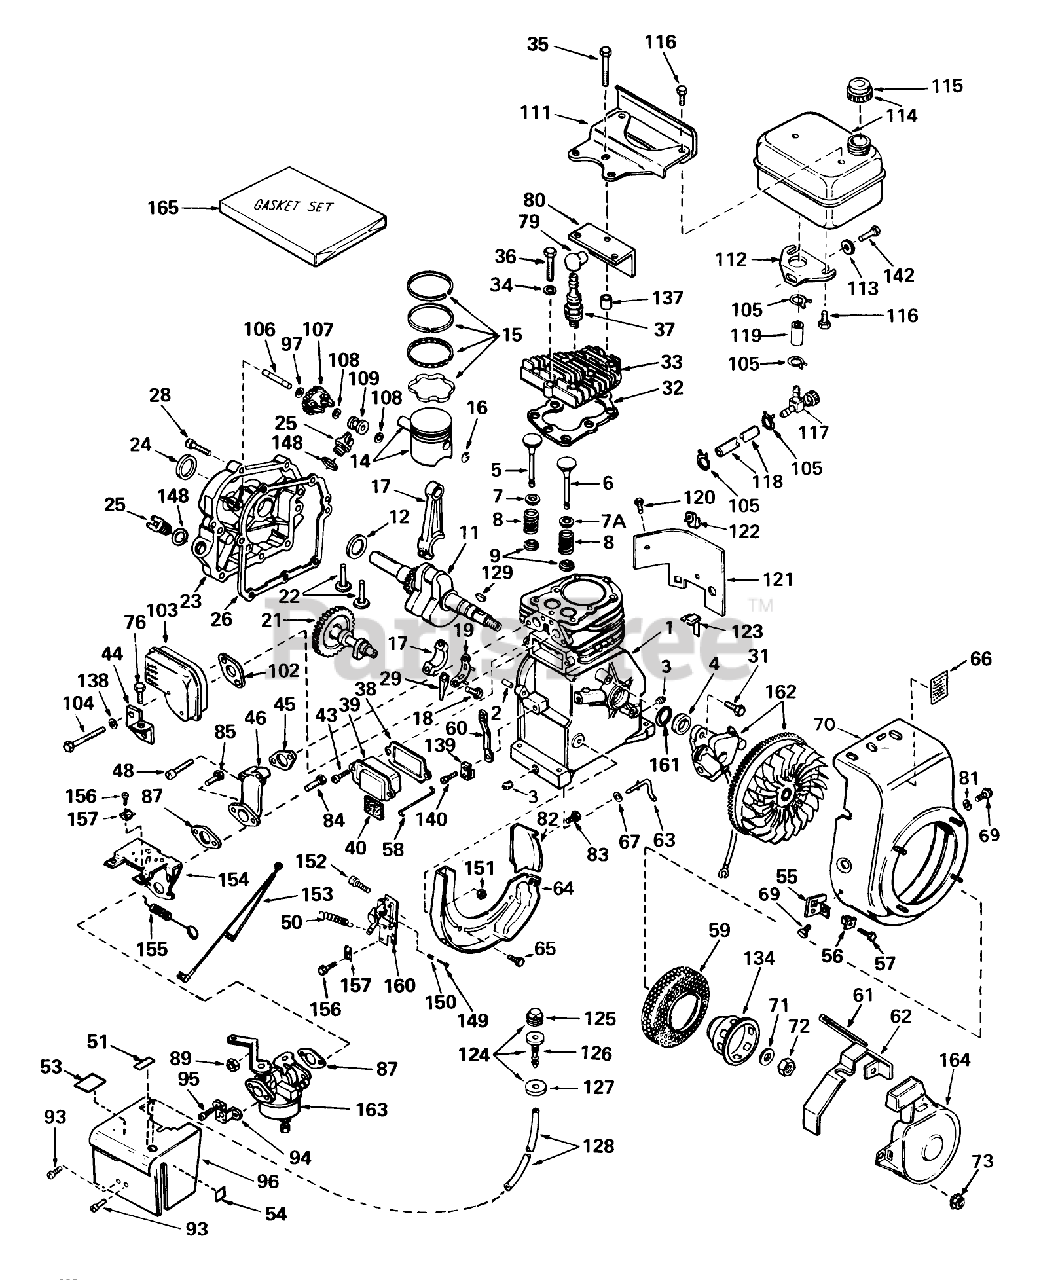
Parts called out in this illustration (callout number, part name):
1	Cylinder Assy. (Incl. Nos.2, 34)
2	Pin-Dowel
3	Plug-Drain, Oil (SQH 1/4-18)
4	Seal-Oil
5	Valve, Intake (Standard) (Incl. Nos. 7, 9 10)
5	Valve, Intake (1/32" Oversize) (Incl. Nos. 7, 9 10)
6	Valve, Exhaust (Standard) (Incl. Nos. 8, 9 10)
6	Valve, Exhaust (1/32" Oversize) (Incl. Nos. 8, 9 10)
7	Cap-Upper Valve Spring
7A	Cap, Upper Valve Spg (Exhaust)
8	Spring-Valve
9	Cap-Valve, Spring
11	Crankshaft Assy.
12	Washer-Thrust
14	Piston Pin Assembly (Incl. 2 of No. 14)(Std.)
14	Piston Pin Assembly (Incl. 2 of No. 14)(.010 Oversize)
14	Piston Pin Assembly (Incl. 2 of No. 14)(.020 Oversize)
15	Ring Set-Piston Std.
15	Ring Set-Piston .010 oversize
15	Ring Set-Piston .020 oversize
16	Ring-Retaining, Piston Pin
17	Rod Assy., Connecting (Incl. Nos. 18 19)
18	Connecting Rod Bolt
19	Plate Lock
21	Camshaft
22	Lifter-Valve
23	Cover, Cylinder (Incl. Nos. 24, 25, 106 148)
24	Seal-Oil
25	Plug-Fill, Oil
28	Screw
29	Dipper-Oil
31	Screw
33	Head Cylinder
34	Washer
35	Screw Hex Hd. Cap
36	Screw
37	Plug, Spark (J17LM or equiv.)
39	Breather Assembly (Incl. Nos. 52 84)
40	Element-Breather
43	Screw
44	Bracket-Cover, Carburetor
46	Pipe-Intake
48	Screw (1/4-20 x 1-19/32)
50	Spring-Extension
51	Decal-Primer
53	Decal, Warning
54	Decal, "Choke"
55	Bracket
56	Grommet
57	Screw
58	Link-Governor to Throttle
59	Screen-Starter
60	Lever, Governor
61	Seal, Snowguard
62	Guard-Starter
63	Rod-Governor
64	Baffle-Blower Housing
65	Screw (1/4-20x19/32)
66	Decal, Instruction
67	Washer-Flat
69	Screw
70	Housing, Blower
71	Washer-Spring
72	Hex Nut
73	Nut and Lock Washer (1/4-28)
76	Screw (10-24 x 3/8)
79	Cover-Spark Plug
80	Baffle-Heat
81	Washer
82	Baffle-Extension
83	Screw-Hex Washer Hd.
85	Screw-Fil. Hd.
89	Nut and Lock Washer (1/4-28)
93	Screw (8-32 X 5/16)
94	Bracket-Choke
95	Screw (10-32 x 1/2)
96	Cover, Carburetor
97	Washer-Flat
103	Muffler
104	Screw-Fil. Hd.
105	Clamp-Line, Fuel
106	Shaft-Governor
107	Governor Gear ASM
108	Ring-Retaining
109	Spool-Governor
111	Bracket, Fuel tank
112	Bracket, Fuel Tank Lower
113	Washer
114	53023/VAR.10/16HP O
115	Cap, Fuel
116	Screw (1/4-15x7/8)
117	Valve-Shut Off
118	Line-Fuel
119	Line-Fuel (8.62)
120	Screw
121	Extension-Blower
122	51004 GIL ROTARY TI
123	Clip-Wire
124	Primer Assy. (Incl. Nos. 89, 90 91)
125	Bulb, Primer
126	Body, Primer
127	Retainer, Primer Bulb
128	Line, Primer
129	Key Flywheel
134	Cup, Starter
137	pacer
138	Washer
139	Clamp-Lever, Governor
140	Screw
142	Screw (1/4-20 X 5/8)
148	Gasket
149	Screw
150	Spring-Compression
151	Nut-Lock
152	Screw, Hex Slotted Hd.
153	Wire, Ground
154	Bracket, Speed Control
155	51011/13 TILL.O/P'7
156	Screw (10-32 x 3/8)
157	Conduit
160	Bracket Assy., Control (Incl. Nos. 149, 150, 151 152)
161	Gasket Stator
162	Magneto (The complete magneto is not available as an assembly.The magneto number is shown for reference purposes only. Order component parts individually as shown in parts list.)
163	Carburetor (Incl. 1 of No. 87)
164	Starter Assy., Rewind
165	Gasket Set
